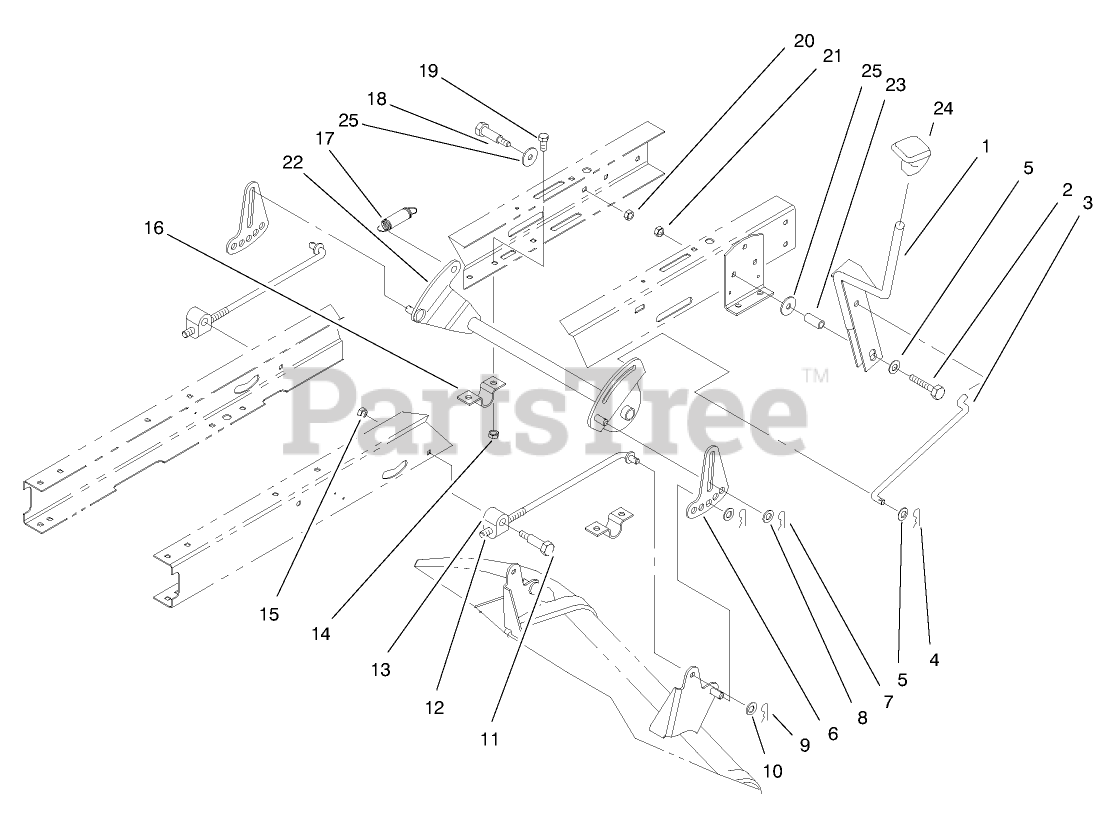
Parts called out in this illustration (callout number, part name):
2	SCREW-HH
3	LINK-HOC
5	WASHER-FLAT
6	LINK-ADJUSTING, HOC
8	WASHER-HARDENED
10	WASHER-FLAT
11	SCREW-SHOULDER, HH
12	ROD-HANGER, REAR
13	TRUNNION-HOC
14	NUT-LOCK, NI
15	NUT-LOCK, NI
16	CLAMP-PIVOT, HOC
17	SPRING-EXTENSION
18	SCREW-SHOULDER, HH
19	SCREW-HH
20	NUT-LOCK, NI
21	NUT-LOCK, NI
22	PIVOT ASM
23	SPACER
24	KNOB-SHIFT
25	WASHER-PIVOT
